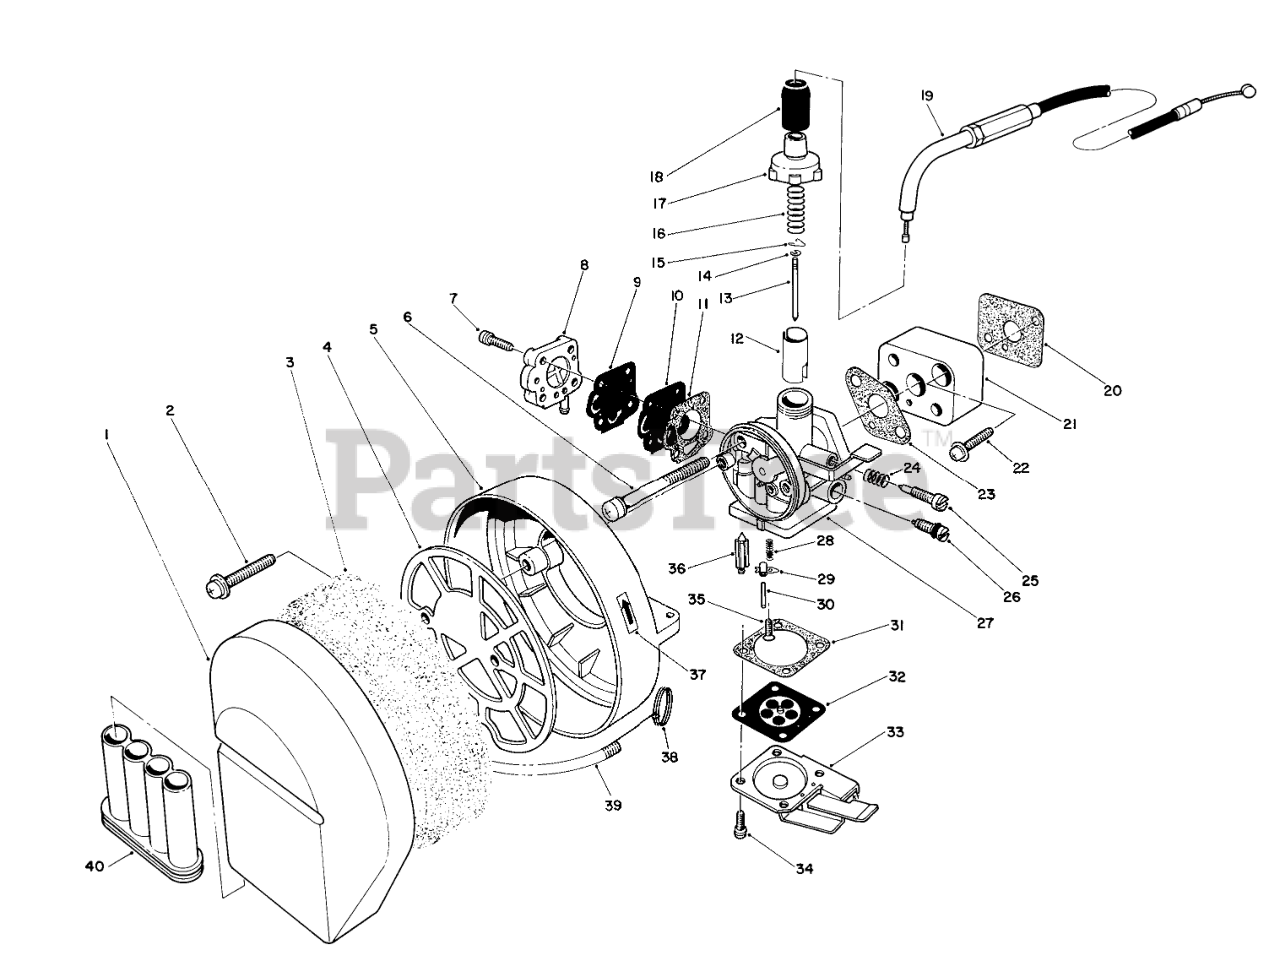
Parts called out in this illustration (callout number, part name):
1	CLEANER COVER
2	SCREW & WASHER
3	CLEANER ELEMENT
5	CLEANER CASE
6	SCREW & WASHER
7	Screw
8	PUMP COVER ASM
9	PUMP DIAPHRAGM
10	PUMP CHECK VALVE
11	PUMP COVER GASKET
12	THROTTLE VALVE
13	Needle-Jet
14	SPRING RETAINER
15	Clip-Needle
16	Spring-Throttle
18	AIR SEAL
19	THROTTLE WIRE
20	GASKET
21	INSULATOR
22	SCREW & WASHER
23	CARBURETOR GASKET
24	SPRING
25	Screw-Adjusting
26	MAIN JET NEEDLE ASM
27	Carburetor Assembly (Incl. Ref. #7-18, 24-26, & 28-36)
28	SPRING
29	FLOAT ARM
30	FLOAT PIN
31	GASKET
32	MAIN DIAPHRAGM ASM
33	COVER
34	SCREW W/ WASHER
35	FLOAT SCREW
36	FLOAT VALVE
37	CHOKE LABEL
38	SPRING
39	SPRING
